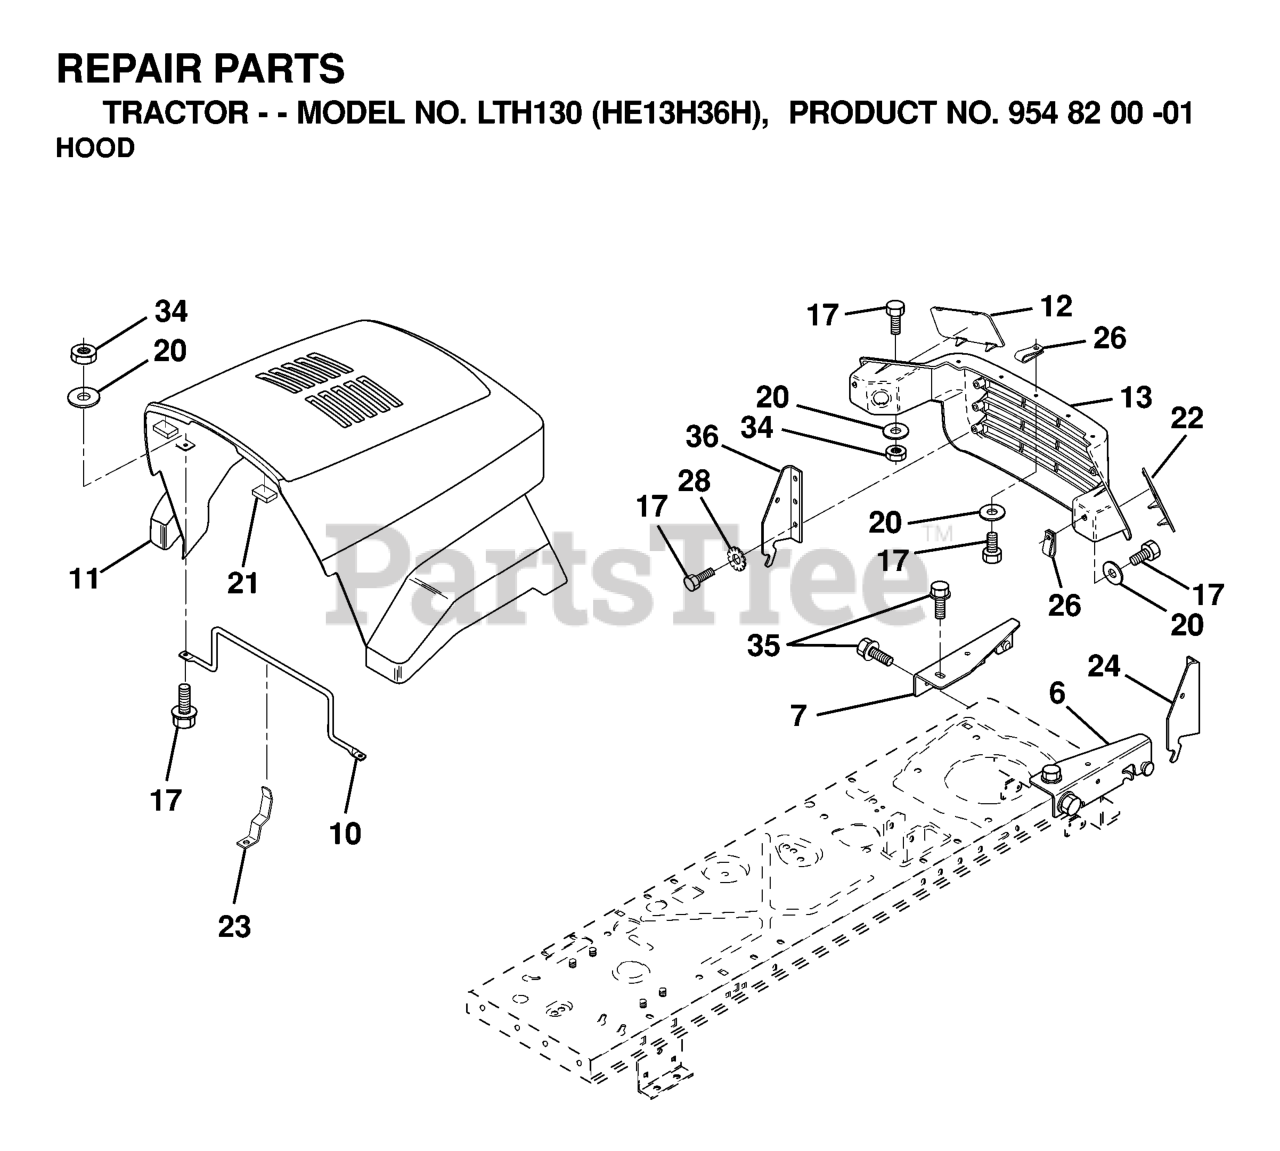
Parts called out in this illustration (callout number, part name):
1	STEERING WHEEL
2	AXLE ASSY
3	SPINDLE.ASM.LH.15"TIRES
4	SPINDLE.ASM.RH.15"TIRES
5	THRUST WASHER
9	BRNG T
10	DRAGLINK.15".TIRES
11	WASHER, LOCK 3/8
13	TUBE, PIVOT AXLE
15	NUT
17	SHAFT ASM STEERING
18	THRUST WASHER
19	STEERING SHAFT SUPPORT
22	SCREW.HX.WSH.HD
23	SHAFT ASSY PITTMAN
25	BRACKET STEERING
26	BUSHING.DRAGLINK (2 2)
27	GEAR.SECTOR
28	WASHER
29	SCREW 3/8-16X3/4
30	COTTER PIN
32	TIE ROD
36	BUSHING, STEERING
37	SCREW.TT.#10-32X.5.3/8.FLANGE
38	CAP.WHEEL.STEERING.GREY
39	Washer 13/32 x 1-1/20 x 11 Gauge
40	GRIPCO NUT
41	STEERING WHEEL ADAPTOR
42	BOOT STEERING
44	EXT SHAFT STEERING
46	CAP.SPINDLE.BLACK
47	ZERK M
51	NUT.71038.31-18.HEX.NYLOCK
54	BOLT.5/16-18X1-1/4 FULL.THREAD
62	STEERING KIT
65	SPACER BRACE AXLE
66	BEARING ARM
67	BOLT CARRIAGE
68	BRACE.AXLE.15"TIRES
79	WASHER
80	BOLT.HX.NYLON3/8-16X
82	HOUR METER
85	FASTENER.XMAS.TREE
